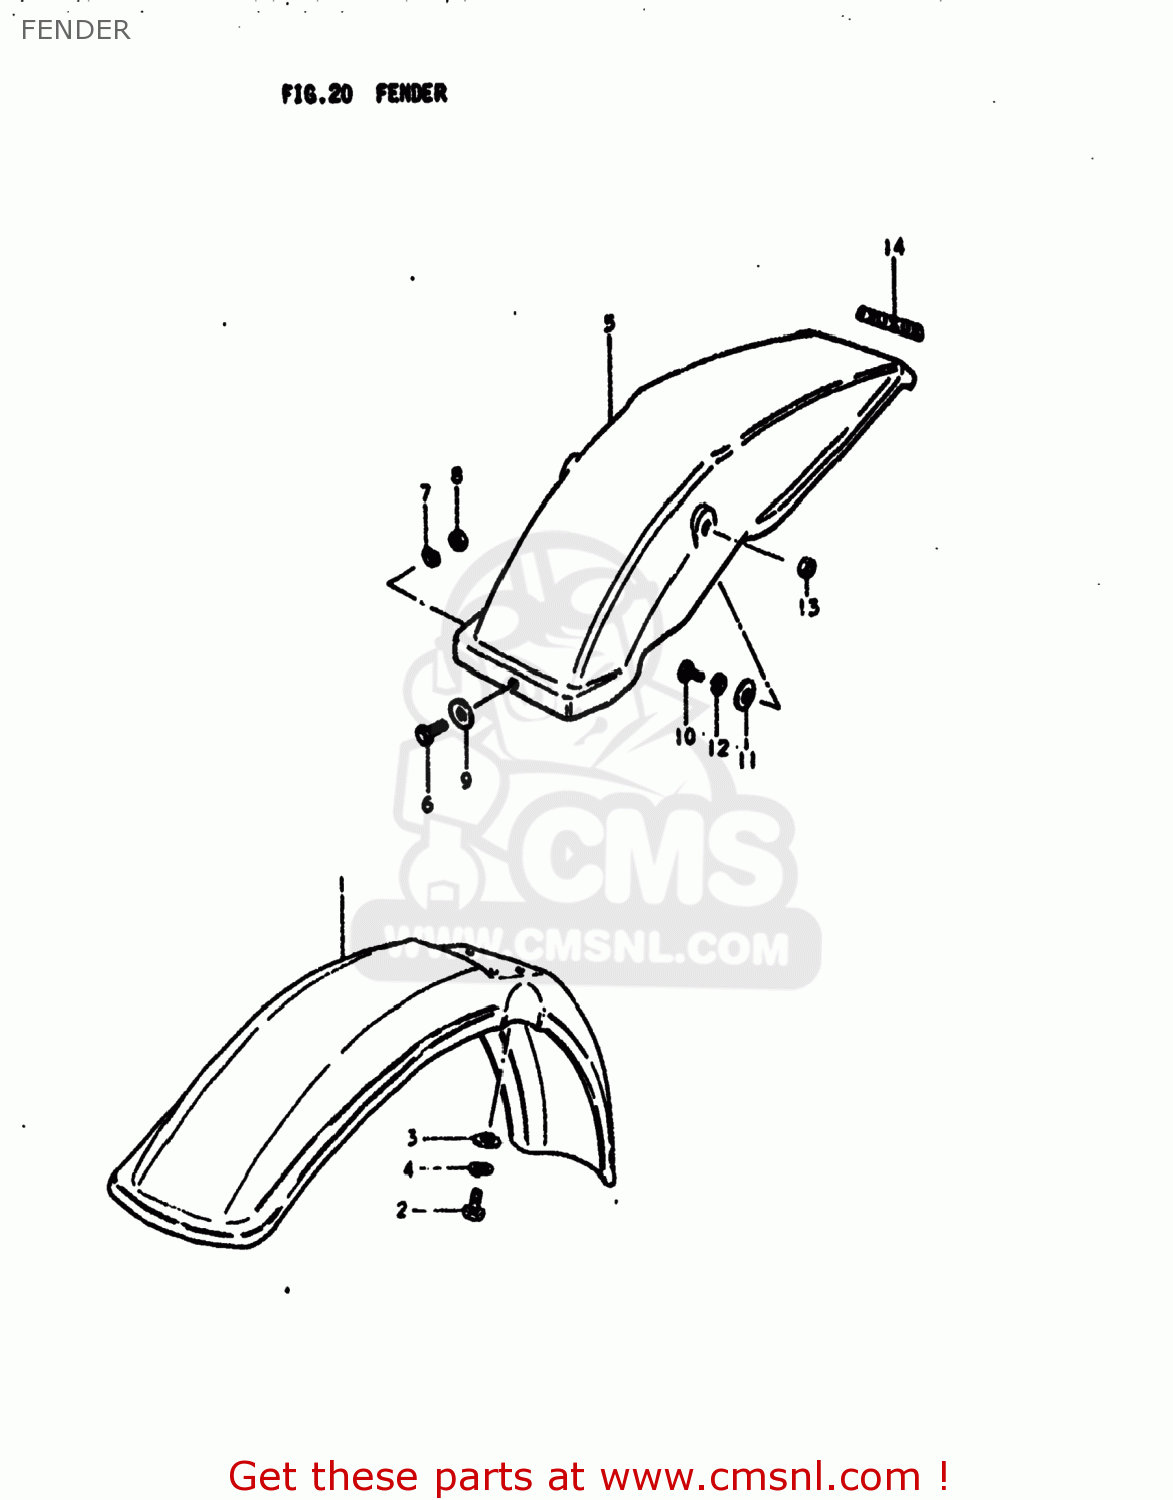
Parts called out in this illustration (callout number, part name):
1	FENDER,FRONT
2	BOLT, UPPER
3	SPACER
4	LOCK WASHER
5	FENDER,REAR
6	BOLT, UPPER
7	LOCK WASHER
8	NUT
9	WASHER
10	BOLT, UPPER
11	WASHER
12	LOCK WASHER
13	NUT 6MM
14	EMBLEM,FRONT FENDER
